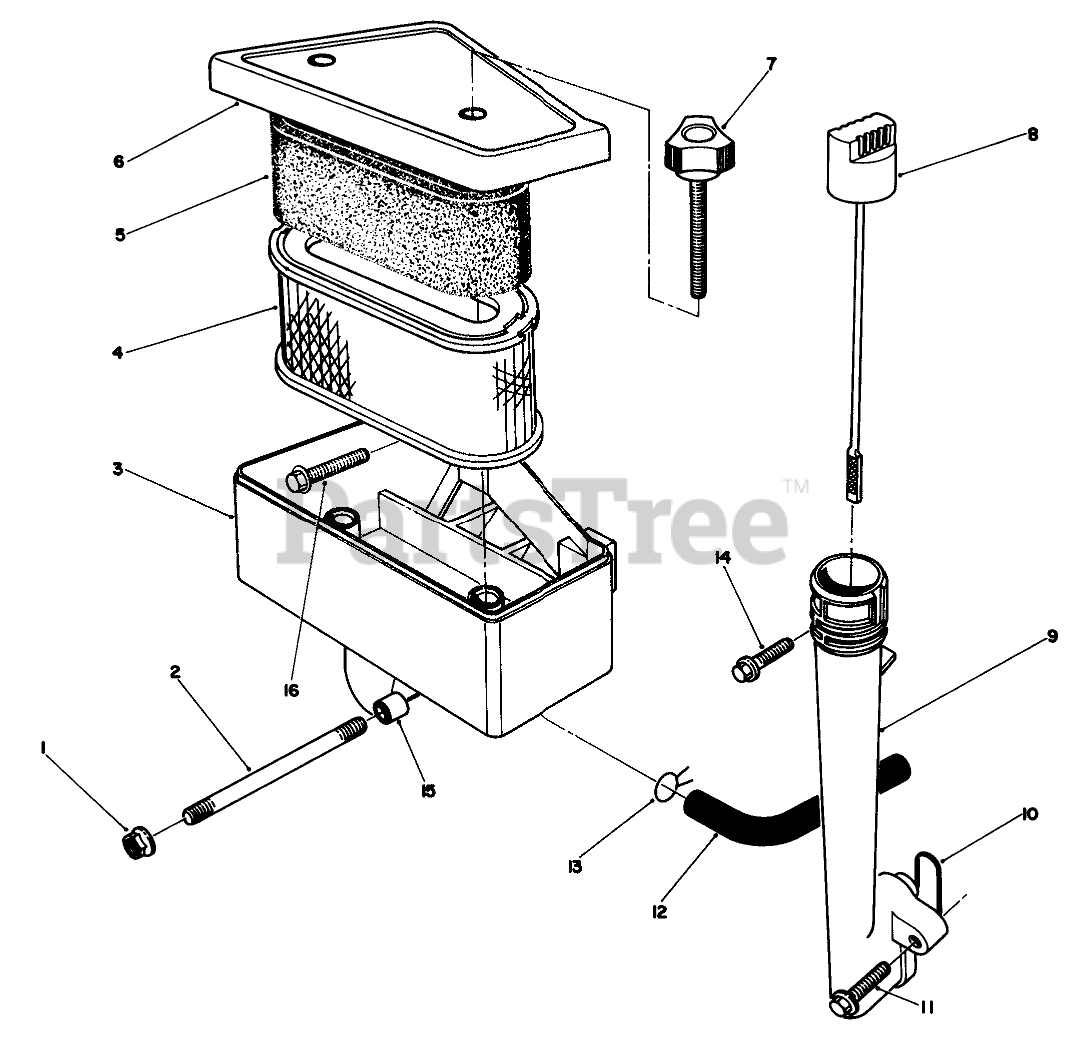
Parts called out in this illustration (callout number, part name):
3	AIR CLEANER BODY
4	Air Filter Assembly (Incl. Ref. #5)
5	Filter-Foam
6	AIR CLEANER COVER B
7	RETAINER - COVER
8	DIPSTICK
10	O-RING
13	CLAMP F/W ENGINE
15	SPACER
16	HEX FL HD M.6X1.0X25MM
